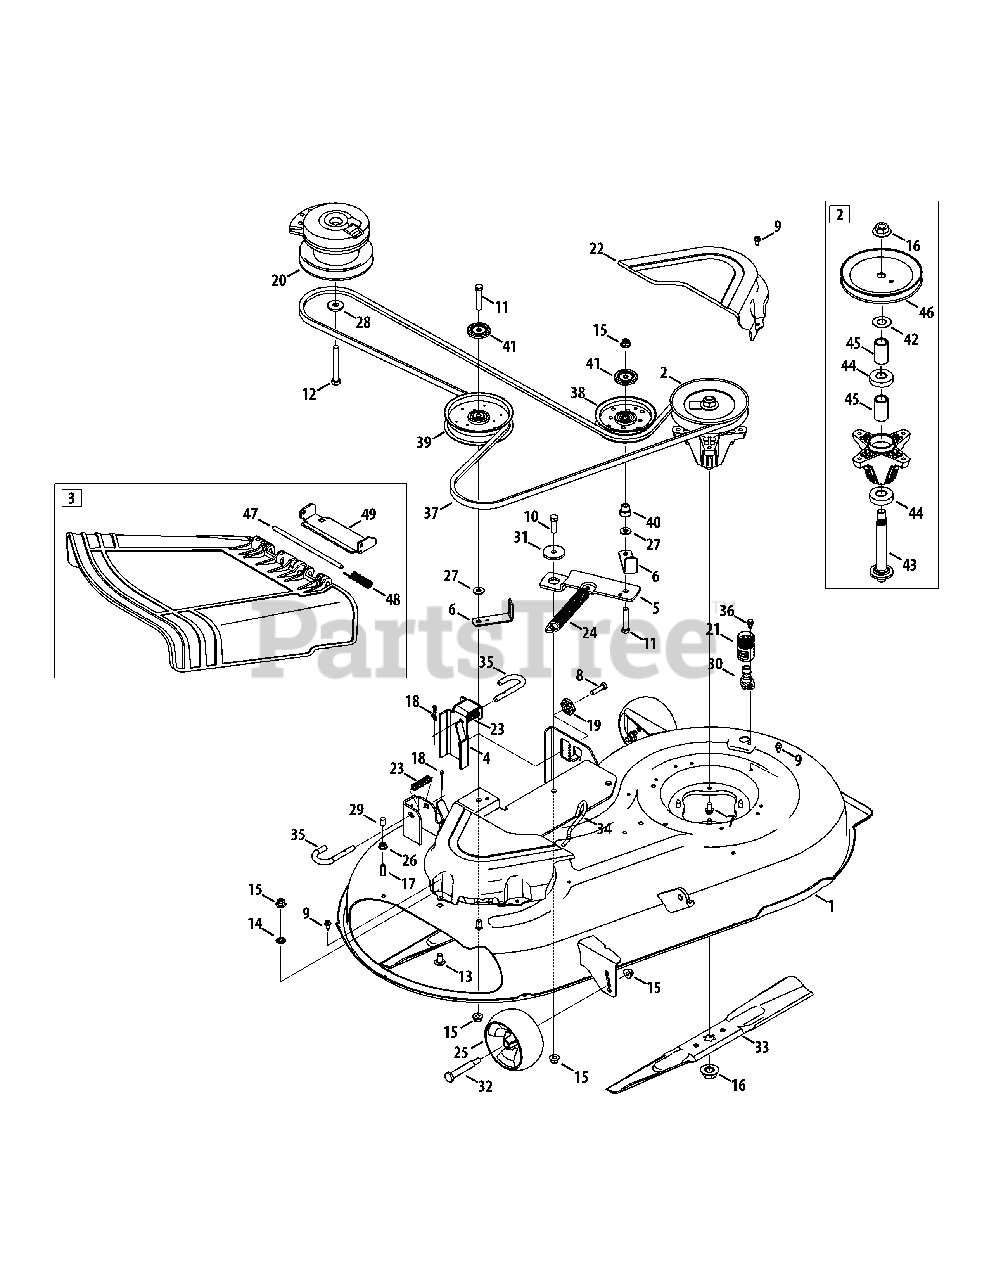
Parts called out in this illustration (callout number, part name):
1	42-Inch Deck
2	Spindle Assembly
3	Discharge Chute Assembly
4	Deck Lift Bracket
5	Pivot Idler Bracket
6	Bracket, Belt Guard
7	Hex Washer Head Screw 5/16-18 x .75
8	Hex Cap Screw 5/16-18 x 1.25
9	Hex Washer Screw 1/4-20 x .625
10	Hex Cap Screw 3/8-16 x 1.25
11	Hex Cap Screw 3/8-16 x 2.00
12	Screw 7/16-20 x 3.25
13	Carriage Screw 3/8-16 x .75
14	Push Nut 3/8
15	Flange Lock Nut 3/8-16
16	Hex Flange Nut 5/8-18
17	Hex Cap Screw 5/16-18 x 1.00
18	Cotter Pin 5/32 x 1.25
19	Deck Adjustment Gear
20	Electric PTO Clutch
21	Water Nozzle Adapter
22	Belt Cover
23	Compression Spring .66 x 1.9
24	Extension Spring .94 Dia. x 7.57
25	Deck Ball Wheel 5.0
26	Flange Lock Nut, 5/16-18
27	Flat Washer .385 x .870 x .092
28	Flat Washer .450 x 1.25 x .164
29	Cap .290 x .500
30	Deck Wash Nozzle
31	Shoulder Spacer .884 x .190
32	Shoulder Screw .5 x 2.5 x 3/8-16
33	Blade 2 in 1, 21.23-Inch Lg.
34	Deck Spring Rod
35	Deck Hanger Rod
36	Shoulder Screw .500
38	Idler Pulley 4.25 Dia.
39	Idler Pulley 5.00 Dia.
40	Shoulder Spacer
41	Pulley Cap
42	Washer .760 x 1.50 x .030
43	Spindle Shaft
44	Ball Bearing
45	Spacer .792 x 1.060 x 1.860
46	Deck Pulley
47	Hinge Pin
48	Torsion Spring
49	Chute Bracket
